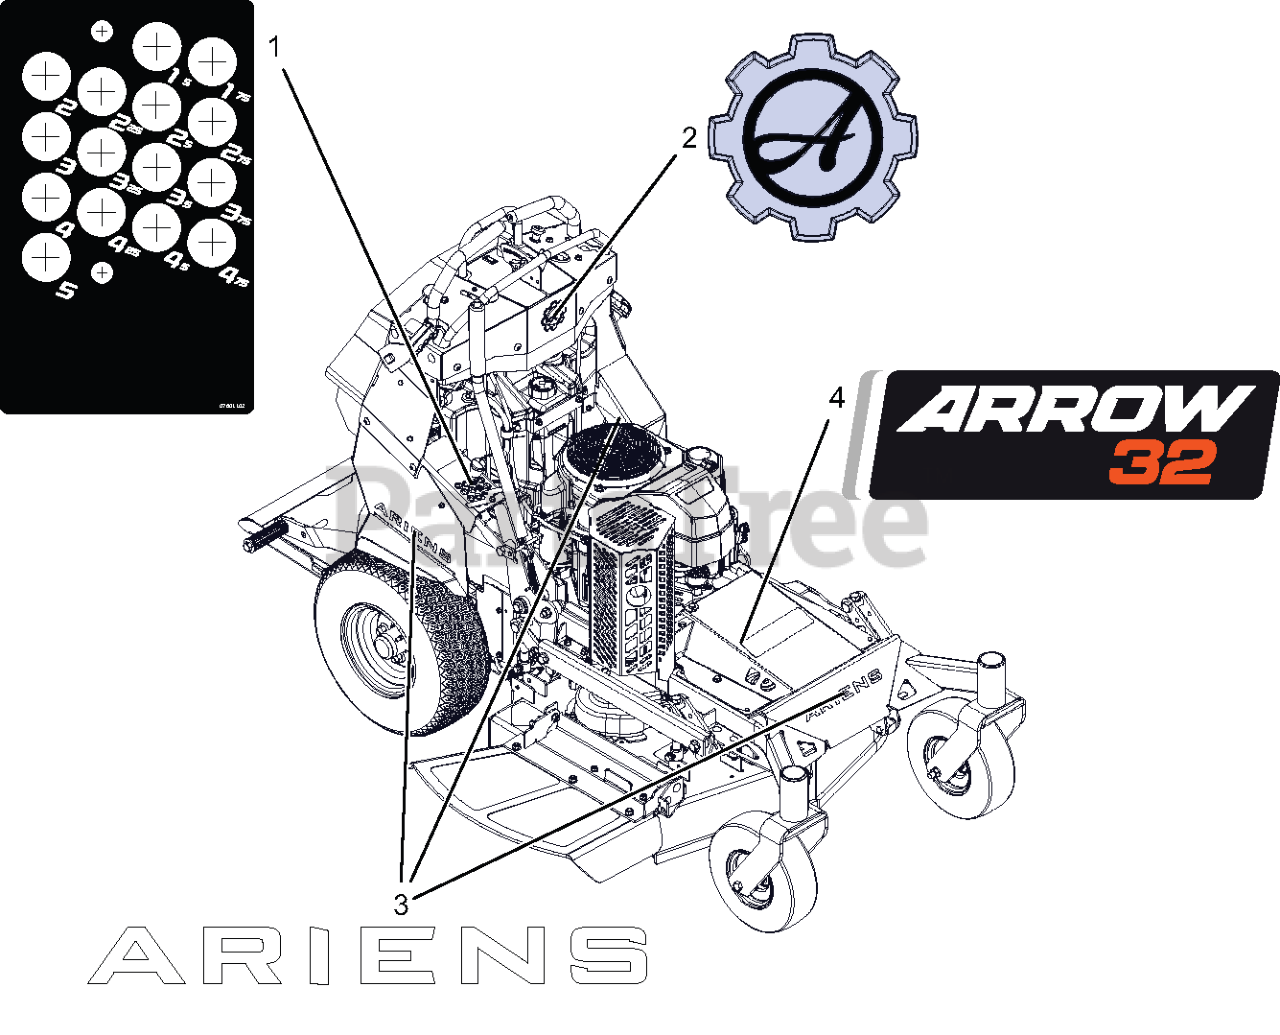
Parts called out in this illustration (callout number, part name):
1	DECAL, PRO STANCE - 32-36 HOC
2	DECAL- ARIENS GEAR BADGE
3	DECAL - ARIENS 9.625"
4	DECAL, ARROW 32
